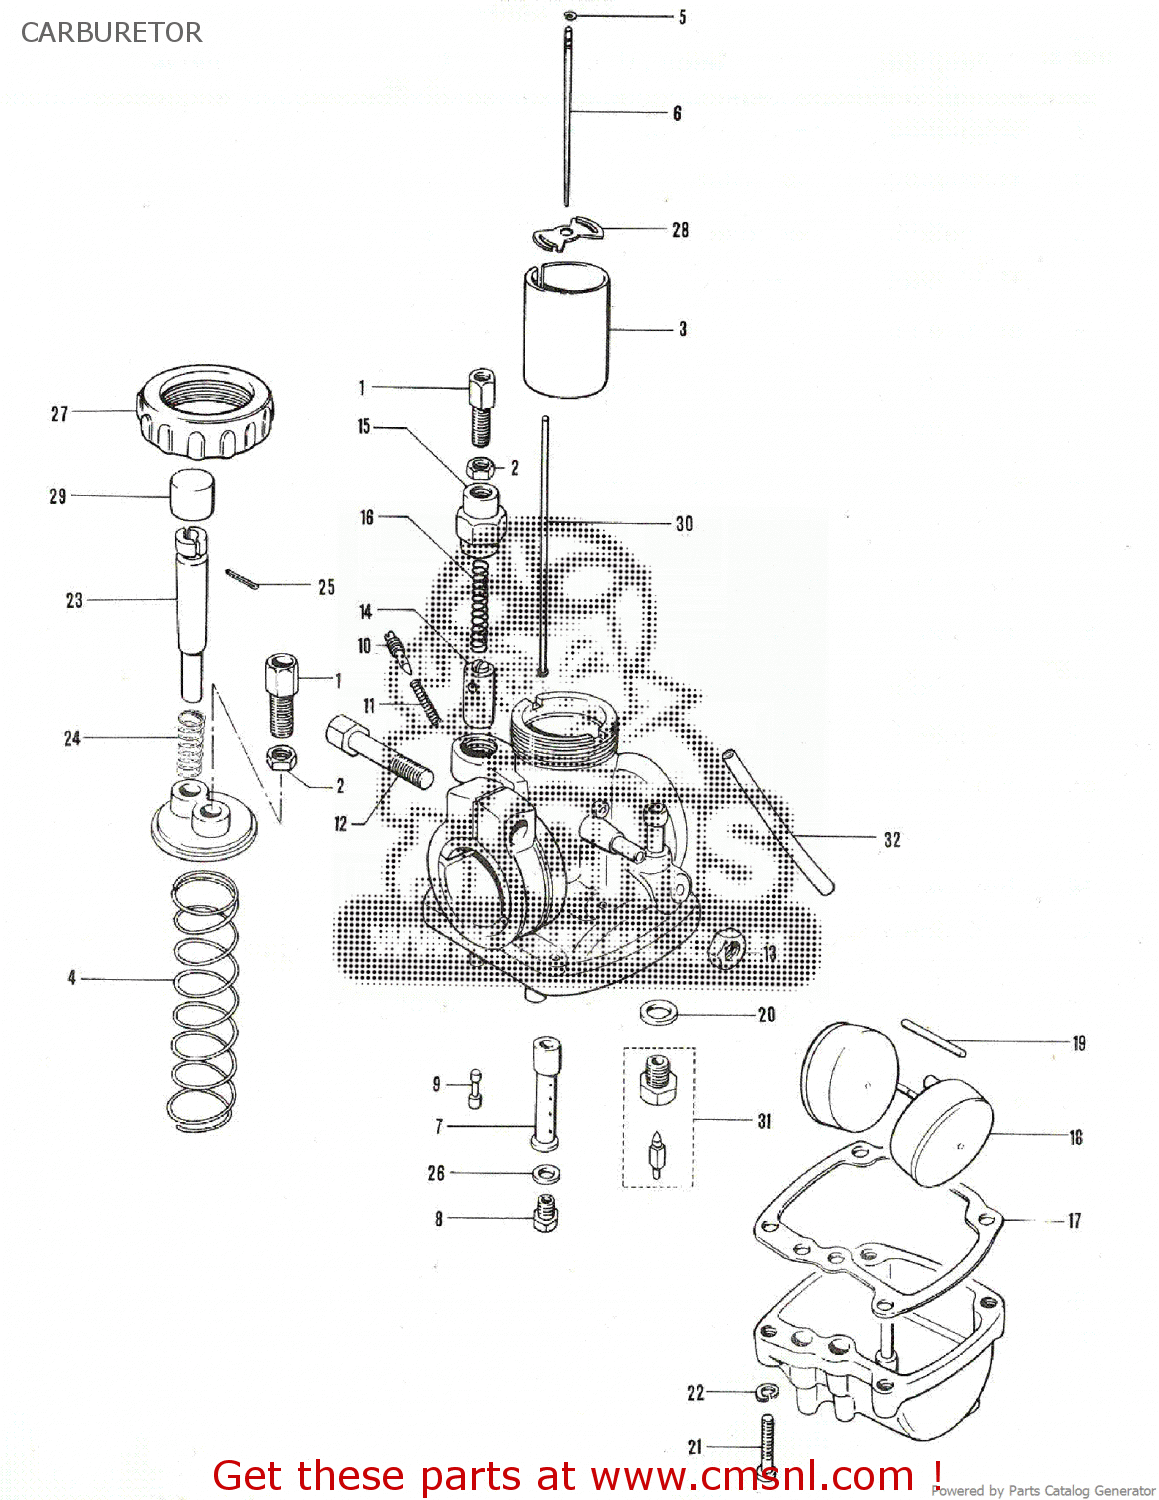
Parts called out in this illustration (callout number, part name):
1	ADJUSTER,CABLE
2	NUT
3	VALVE,THROTTLE
4	SPRING,THROTTLE VALVE
5	CLIP,NEEDLE
6	JET NEEDLE
7	JET,NEEDLE
8	JET MAIN (160)
9	JET
10	SCREW,PILOT AIR
11	SPRING
12	BOLT,CARBURETOR CLIP
13	NUT
14	PLUNGER,STARTER
15	CAP,STARTER PLUNGER
16	SPRING
17	GASKET,FLOAT CHAMBER
18	FLOAT
19	PIN,FLOAT
20	GASKET,NEEDLE VALVE (NAS)
21	SCREW
22	LOCK WASHER
23	SCREW,THROTTLE STOP
24	SPRING,THROTTLE STOP SCREW
25	PIN
26	WASHER
27	CAP,MIXING CHAMBER
28	STOPPER,NEEDLE CLIP
29	CAP,THROTTLE VALVE STOP SCREW
30	ROD,THROTTLE VALVE ADJUST
31	VALVE ASSY,NEEDLE
